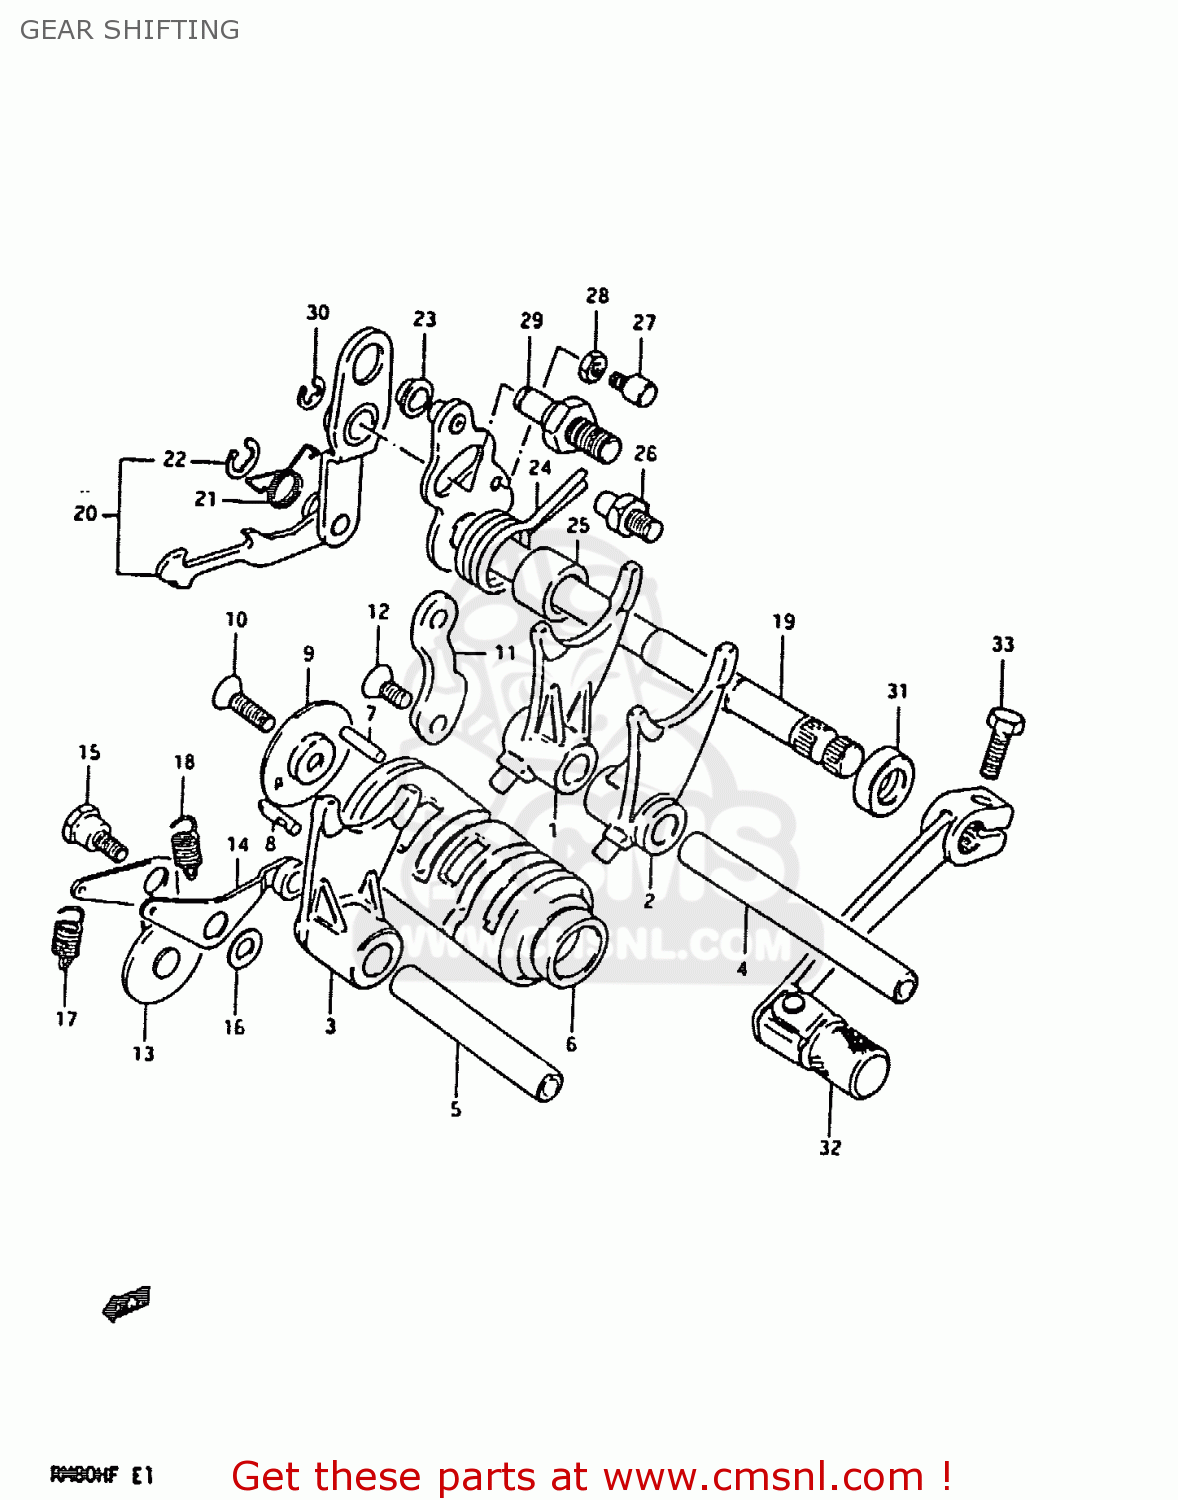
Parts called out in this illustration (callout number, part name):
1	FORK,GEAR SHIFT NO.1
2	FORK,GEAR SHIFT NO.2
3	FORK,GEAR SHIFT NO.2
4	SHAFT,GEAR SHIFT FORK
5	SHAFT,GEAR SHIFT FORK
6	CAM,GEAR SHIFT
7	PIN(4X15.8)
8	PIN
9	RETAINER,GEAR SHIFT CAM
10	SCREW
11	GUIDE,GEAR SHIFTING CABLE
12	SCREW
13	STOPPER,SHIFT CAM
14	STOPPER,GEAR SHIFT CAM
15	BOLT(6X18.3)
16	WASHER
17	SPRING
18	SPRING
19	SHAFT,GEAR SHIFT
20	PAWL,GEAR SHIFT
21	SPRING
22	E RING
23	SPACER(7X10X5)
24	SPRING
25	SPACER(12X20X15.3)
26	STOPPER,GEAR SHIFT CAM
27	BOLT,GEAR SHAFT RETURN SPR SET
28	NUT 6MM
29	STOPPER,GEAR SHIFT CAM
30	E RING 6MM
31	OIL SEAL
32	LEVER ASSEMBLY,GEAR SHIFTING
33	BOLT
